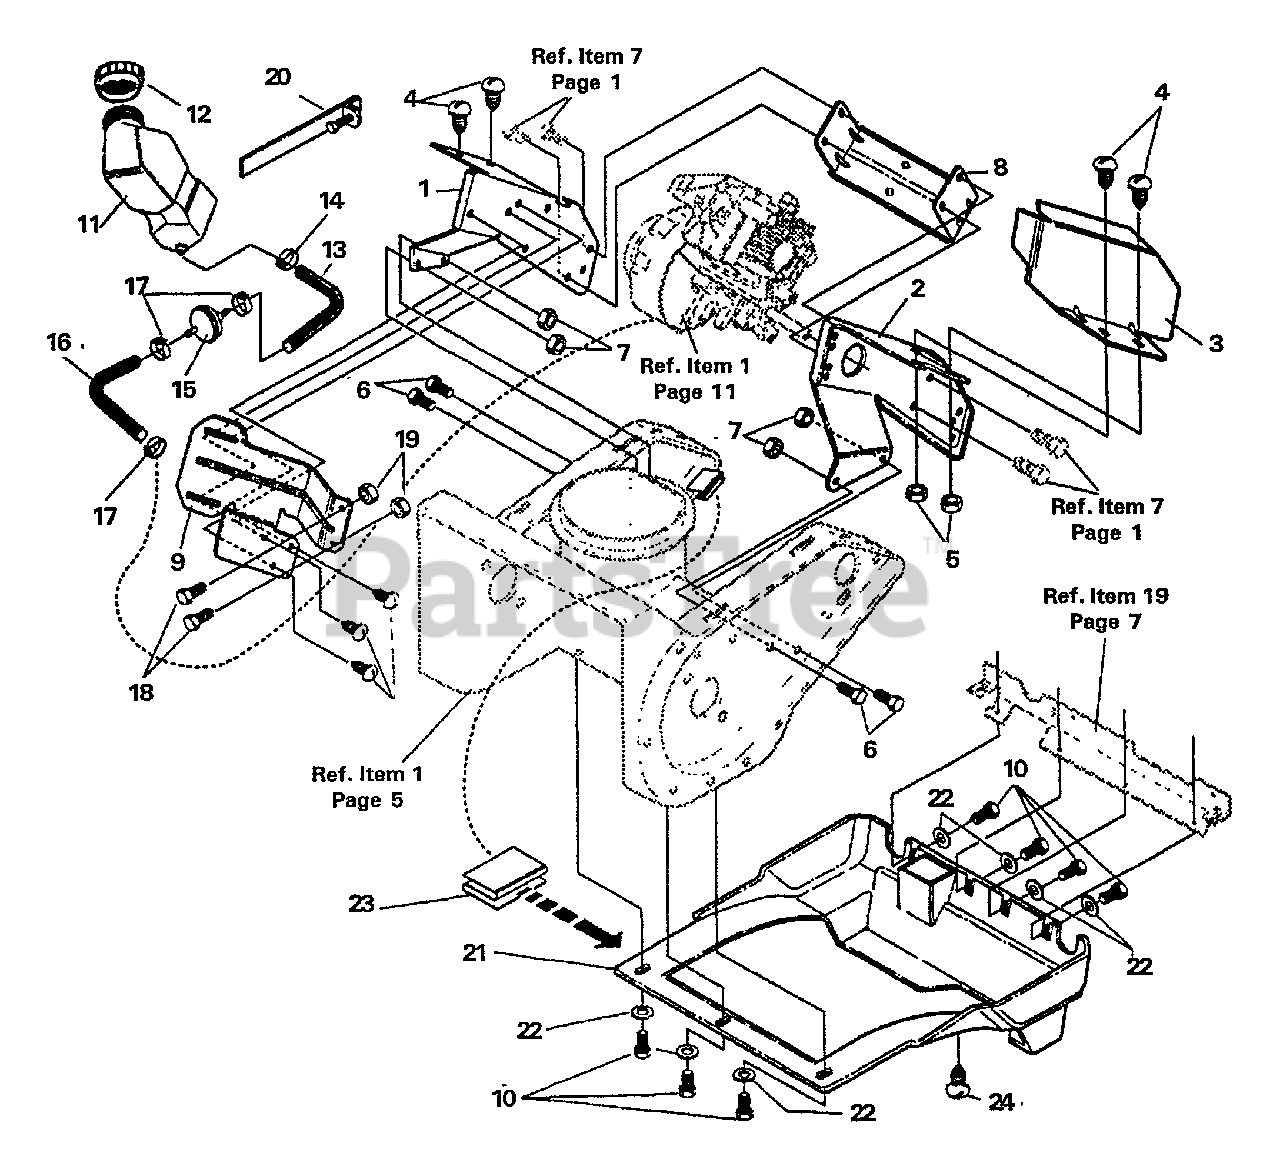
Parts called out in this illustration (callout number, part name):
1	PLATE, REAR MOUNT -- RIGHT
2	PLATE, REAR MOUNT -- LEFT
3	SHIELD, HEAT
4	SCREW
5	LOCKNUT - 1/4-20
6	SCREW - 5/16-18 X 1/2"
7	NUT - 5/16-18
8	SUPPORT, FRAME
9	BRACKET, FUEL TANK
10	SCREW - 10-24 X .63"
11	TANK, FUEL - 6.2 QUART
12	CAP, FUEL
13	TUBING, GAS LINE 8"
14	CLAMP, HOSE
15	FILTER, FUEL
16	TUBING, GAS LINE 30"
17	CLAMP, HOSE
18	SCREW - 10 X 24 X .50"
19	LOCKNUT - 10-24
20	CLAMP, WORM DRIVE
21	SHROUD, BOTTOM
22	WASHER
23	CLIP
24	SCREW - 10-16 X .50"
